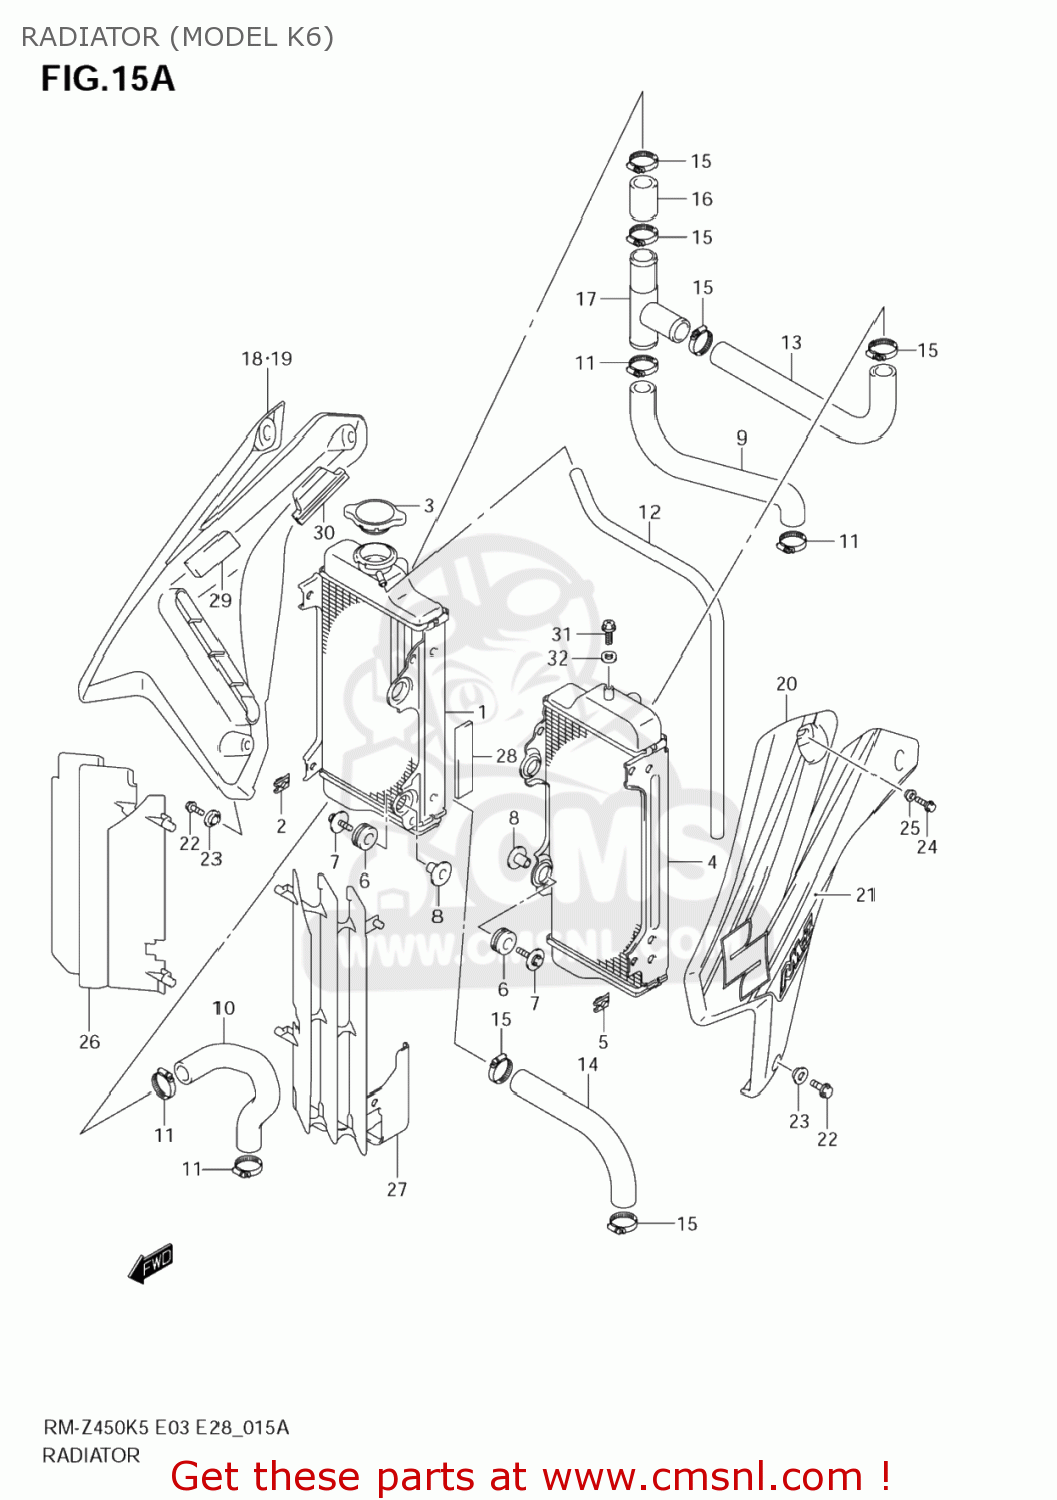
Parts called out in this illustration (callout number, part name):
1	RADIATOR,WATER,R
2	NUT
3	CAP COMP,RADIATOR
4	RADIATOR,WATER,L
5	NUT
6	CUSHION,RADIATOR LWR
7	BOLT(6X25)
8	SPACER(6.5X10.5X14.1)
9	HOSE,RADIATOR INLET
10	HOSE,RADIATOR OUTLET
11	CLAMP
12	HOSE(5X8X2000)
13	HOSE,RADIATOR JOINT UPR NO.1
14	HOSE,RADIATOR JOINT LWR
15	CLAMP
16	HOSE,RADIATOR JOINT UPR NO.2
17	JOINT,RADIATOR HOSE
18	COVER,RADIATOR,R(YELLOW)
19	TAPE,RADIATOR COVER,R
20	COVER,RADIATOR,L(YELLOW)
21	TAPE,RADIATOR COVER,L
22	BOLT(6X12)
23	WASHER,RR BRAK
24	BOLT(6X16)
25	SPACER(6.3X10X6)
26	LOUVER,RADIATOR,R
27	LOUVER,RADIATOR,L
28	CUSHION,RADIATOR
29	CUSHION,RADIATOR COVER NO.2
30	CUSHION,RADIATOR COVER NO.1
31	UNION BOLT,AIR VENT
32	GASKET(6.4X11.5X0.8) (NAS)
